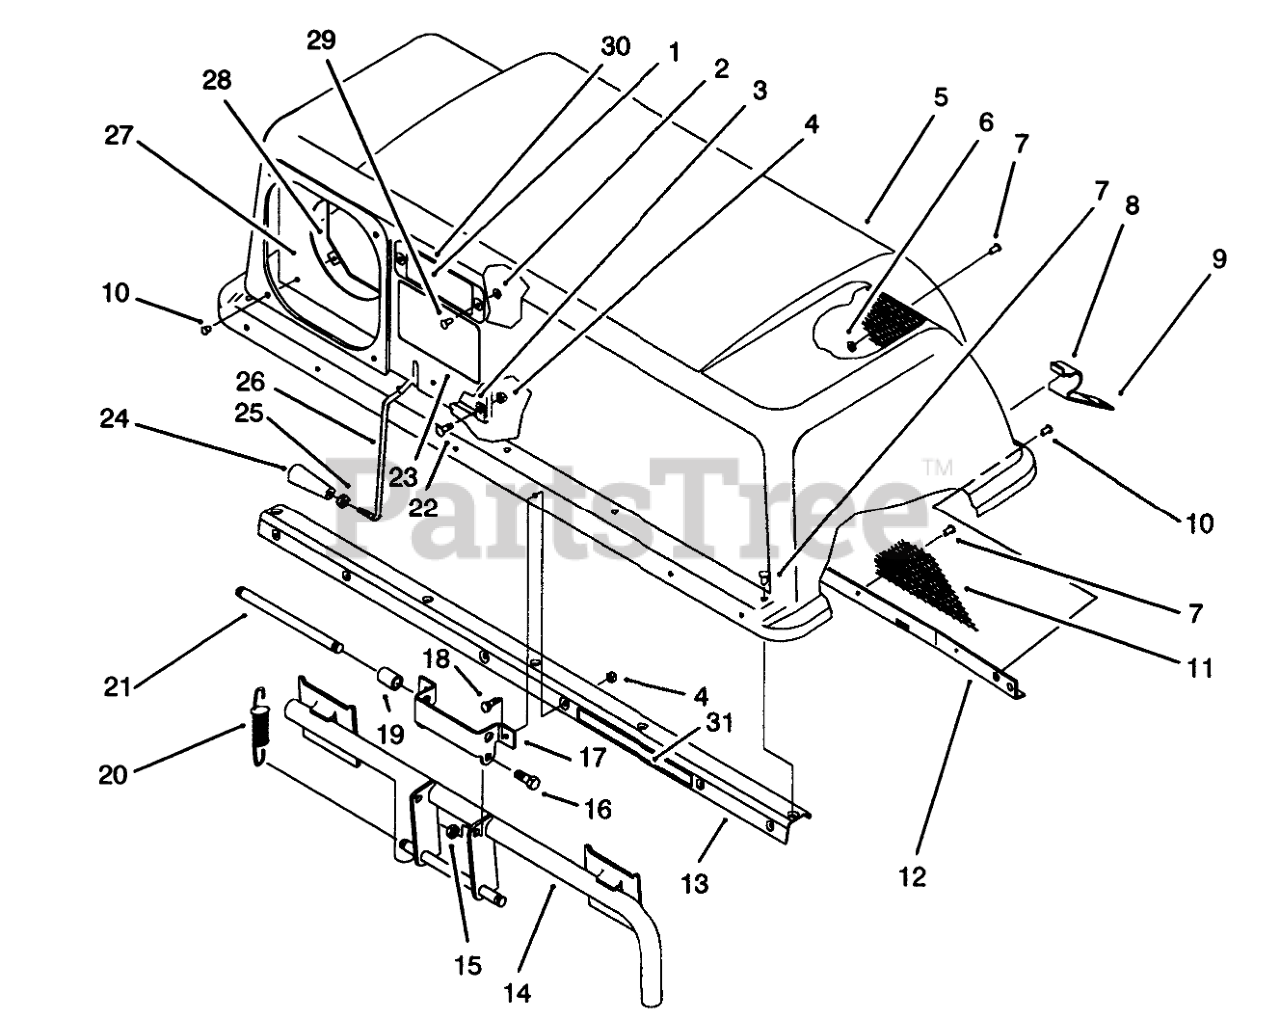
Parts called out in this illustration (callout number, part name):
1	DECAL-DANGER
2	WASHER-PLAIN
3	Clip
4	NUT-LOCK, NI
5	Bag Top Assembly (Incl. Ref. #1, 2, 29, & 30)
6	Washer
7	RIVET-BLIND
8	Latch-Bag
10	Pop Rivet
11	SCREEN-BAGGER
12	SUPPORT-SCREEN B
13	Stiffener Assembly (Incl. Ref. #31)
14	FRAME ASM
15	NUT-LOCK, NI
16	SCREW-HH
17	HINGE-BAG TOPB
18	SCREW-HH
19	SPACER
20	SPRING-EXTENSION
21	PIN-SPRING
22	Screw
23	DECAL
24	HANDLE-TAPERED
25	NUT-JAM
26	FEELER-FILL, BAG
27	SEAL-CHUTE
28	CLAMP-SEAL
29	RIVET - POP
30	PLATE-MTG. DECAL B
31	Decal
